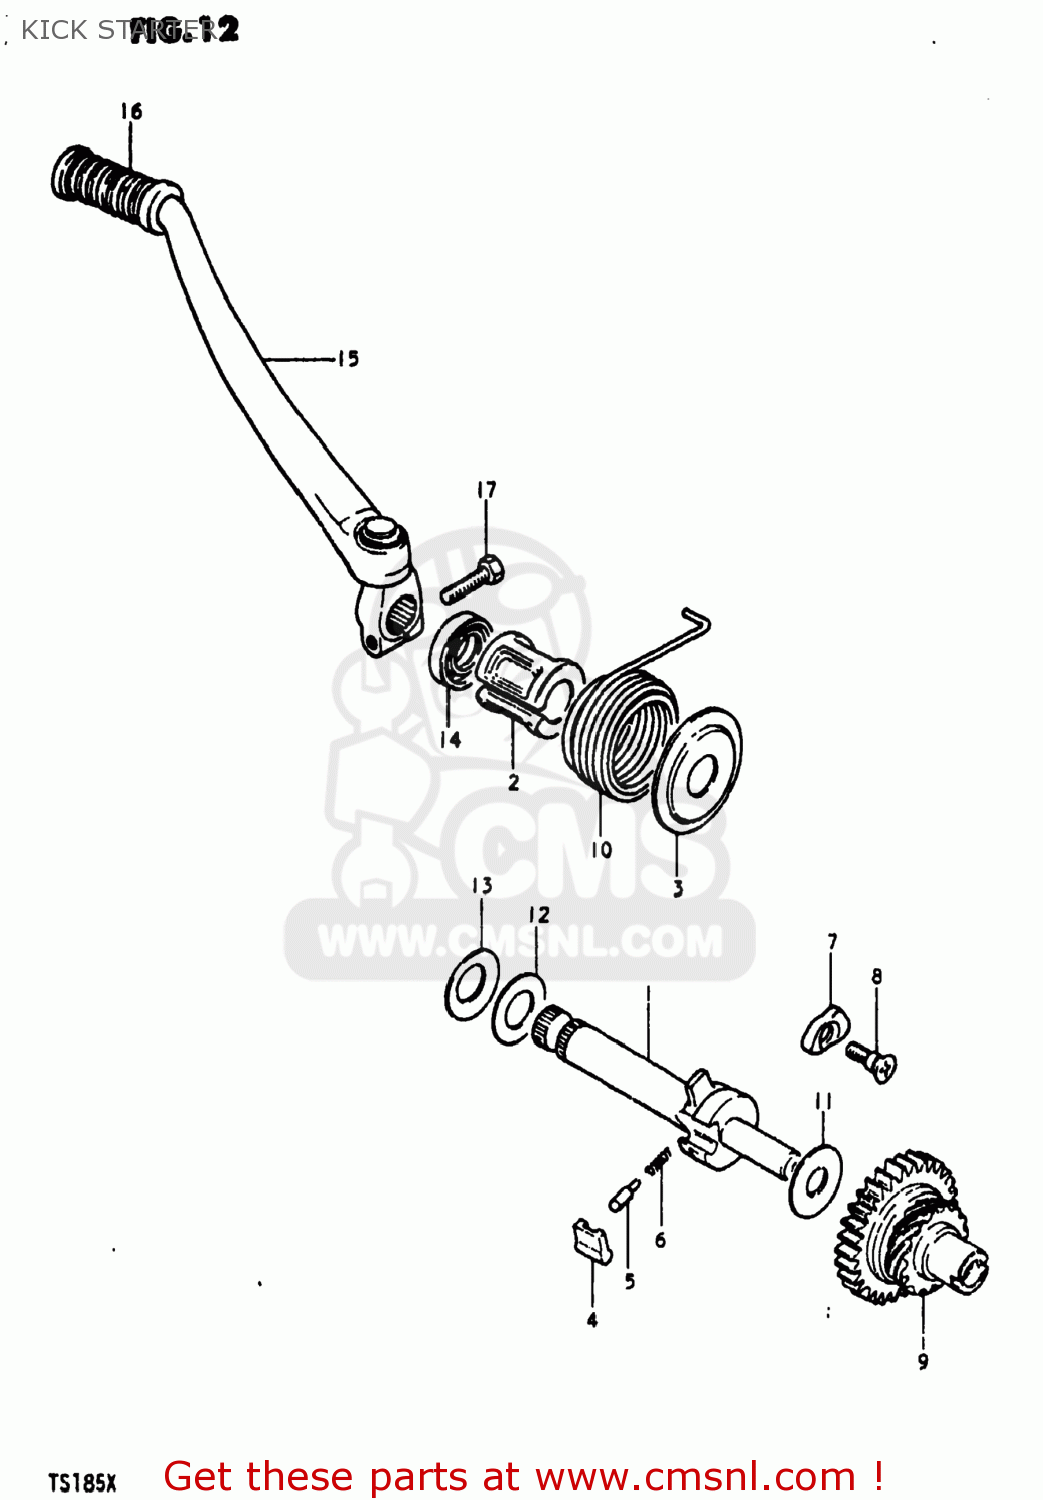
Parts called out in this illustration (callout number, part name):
1	SHAFT,KICK STARTER
2	GUIDE,KICK STARTER SFT SPRING
3	HOLDER,KICK STARTER SHAFT SPR
4	PAWL,KICK STARTER
5	PIN(5X15.5)
6	SPRING
7	LIFTER,KICK STARTER PAWL
8	SCREW(6X19)
9	GEAR,KICK STARTER DRIIVE
10	SPRING
11	WASHER(12X30X3)
12	WASHER(16X30X0.5)
13	WASHER
14	SEAL,OIL(16X30X8)
15	LEVER ASSEMBLY,KICK STARTER
16	RUBBER,KICK STARTER PEDAL
17	BOLT
